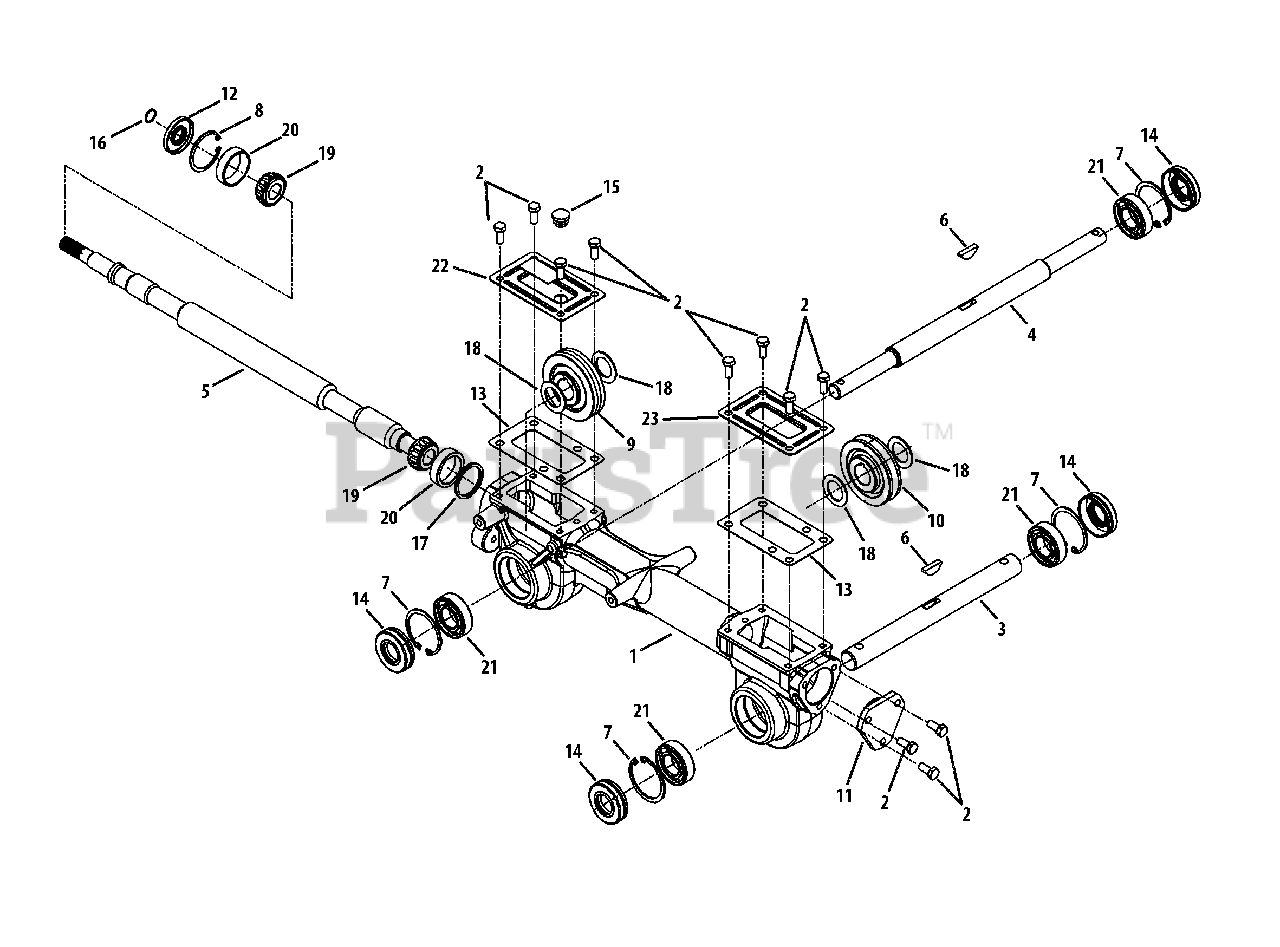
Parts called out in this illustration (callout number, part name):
1	Housing, Transmission
2	Hex Screw, 5/16-18, .75, Gr5
3	Shaft, Tiller
4	Shaft, Wheel
5	Shaft, Worm
6	Key, Hi Pro .25 x 1.062
7	Retaining Ring
8	Retaining Ring, Int
9	Worm Gear, 61t, RH
10	Worm Gear, 30t, LH
11	Bearing Cover
12	Seal, Oil, .750 Shaft x 1.783 Bore
13	Gasket, Gear Housing
14	Seal, Oil, 1.00 Shaft x 2.00 Bore
15	Rubber Plug, Oil
16	Wire Ring
17	Washer, Flat, 1.50 x 1.75 x .062
17	Washer, Flat, 1.50 x 1.75 x .005
17	Washer, Flat, 1.50 x 1.75 x .03
17	Washer, Flat, 1.50 x 1.75 x .010
18	Washer, Flat, 1.010 x 1.56 x .060
19	Cone Bearing
20	Bearing Cup
21	Ball Bearing
22	Cover, Transmission
23	Cover, Transmission
